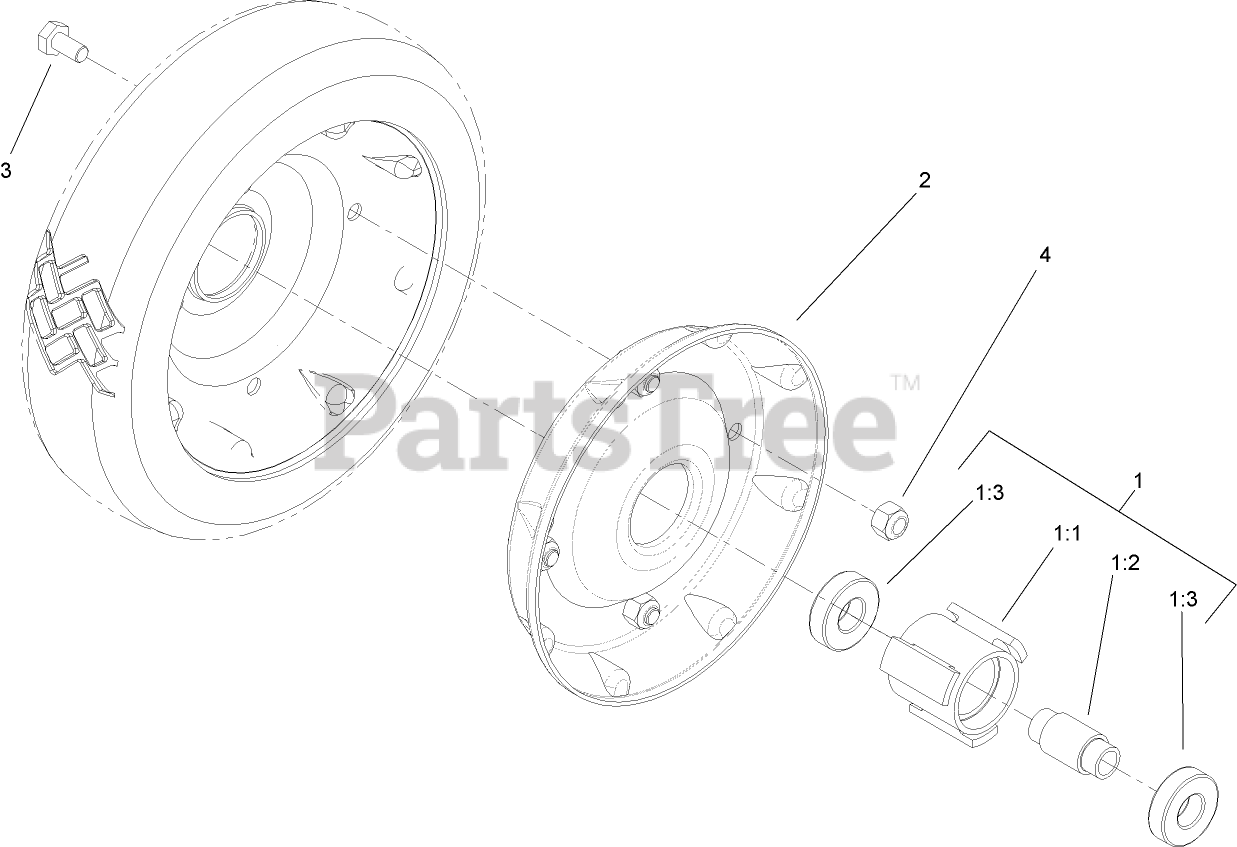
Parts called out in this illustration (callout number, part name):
1	Loose Parts Package
1:1	HUB-BEARING
1:2	SPACER-BEARING
1:3	BEARING-WHEEL
3	SCREW-HH
4	NUT-LOCK, NI
